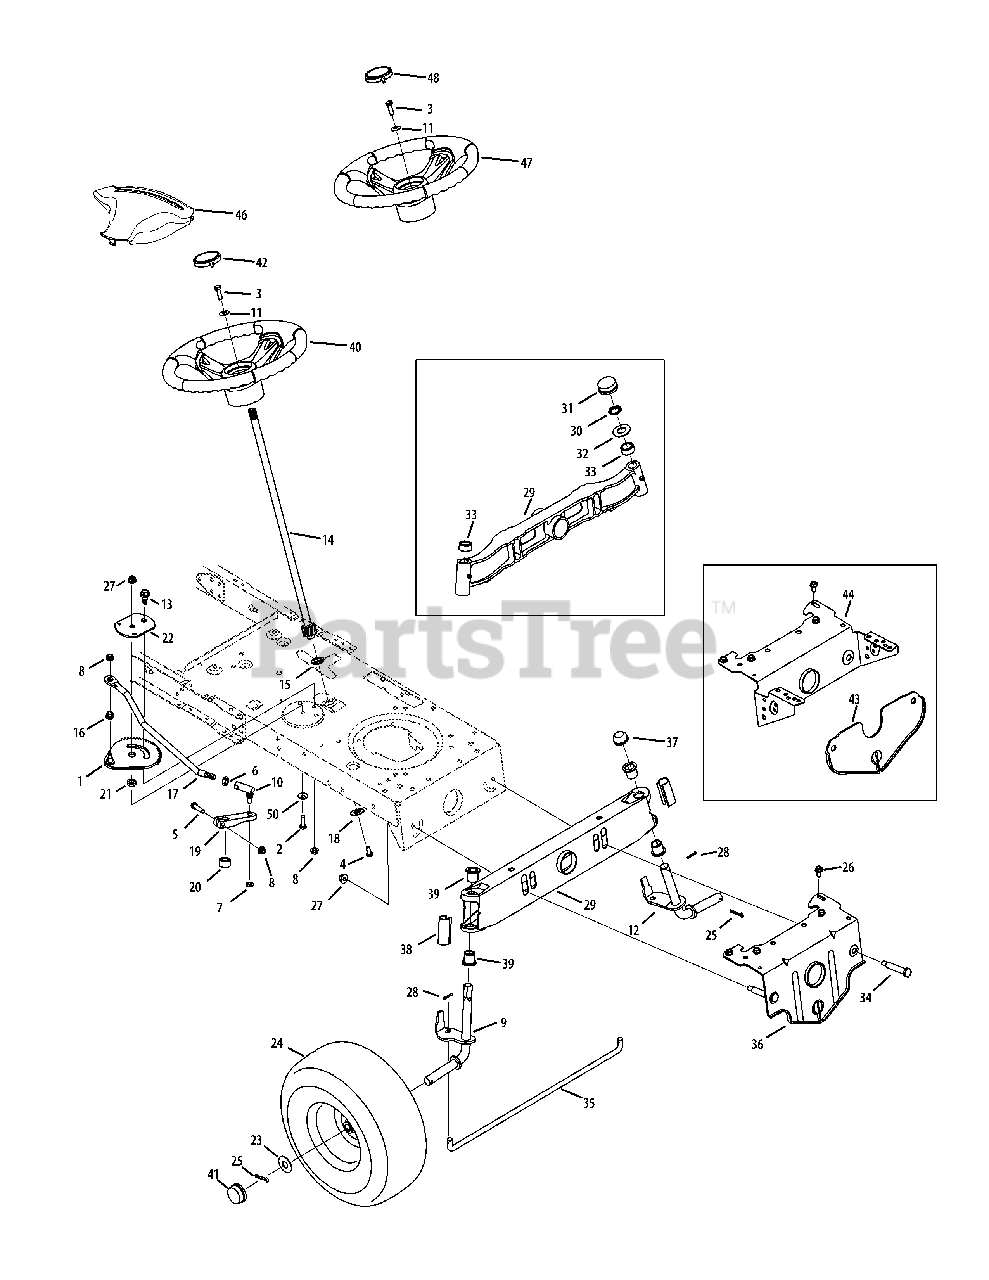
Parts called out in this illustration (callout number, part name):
1	Steering Gear Assembly
2	Hex Hd. Cap Scr 3/8-16 x 1,00 Gr. 5
3	Hex Screw 5/16-18 x 1.00 Special
4	Machine Screw 5/16-18 x .75
5	Hex Screw 5/16-18 x 1.75" Lg.
6	Hex Jam Nut 7/16-20
7	Hex Cent-L Nut 3/8-24 Gr. B
8	Flange Locknut 5/16-18 Gr. F, Nylon
9	Axle Assembly, RH
9	Axle Assembly, RH (w/46" deck)
10	Ball Joint, 7/16 - 20
11	Cupped Washer .345 ID x .88 OD x .060
12	Axle Assembly, LH
12	Axle Assembly, LH (w/46" deck)
13	Shoulder Screw .435 x .3485, 5/16-18
14	Steering Shaft, 5/8 Spline
15	Hex Flange Bearing 5/8
16	Plastic Bushing .375 ID x .5
17	Steering Drag Link
18	Cap, 1.25 x .16
19	Steering Block
20	Spacer .710 ID x .125 OD x .56
22	Plate
23	Flat Washer .781 ID x 1.59 OD Special
24	Wheel Ass’y Complete 15 x 6 x 6
24	Tire Only
24	Air Valve
25	Cotter Pin 5/32 x 1.25
26	S-Tapp Scr 5/16-18 x .75
27	Flange Lock-Nut 3/8-16 Gr. F Nylon
28	Cotter Pin 1/8" Dia x .75
29	Pivot Bar (stamped steel)
30	Push Nut 3/4"
31	Axle End Cap
32	Flat Washer .78 x 1.59 x .060
33	Spacer .71 x .125 x .56
34	Shoulder Screw .500 x 2.380, 3/8-16
35	Tie Rod
36	Pivot Bar Bracket
37	Push Cap, .750
38	Axle End Cap, Standard
39	Flange Bearing .760 ID x .937 OD
40	Steering Wheel, Standard Grip, 3 spoke
41	Plastic Hub Cap
42	Steering Wheel Cap (w/o logo)
42	Steering Wheel Cap (sprig logo)
43	Front Deck Hanger Bracket
44	Pivot Bracket
46	Steering Wheel Cover
46	Steering Wheel Cover - Troy
47	Steering Wheel, 4 spoke
48	Steering Cap
50	Cupped Washer .390 x 1.130 x .062
